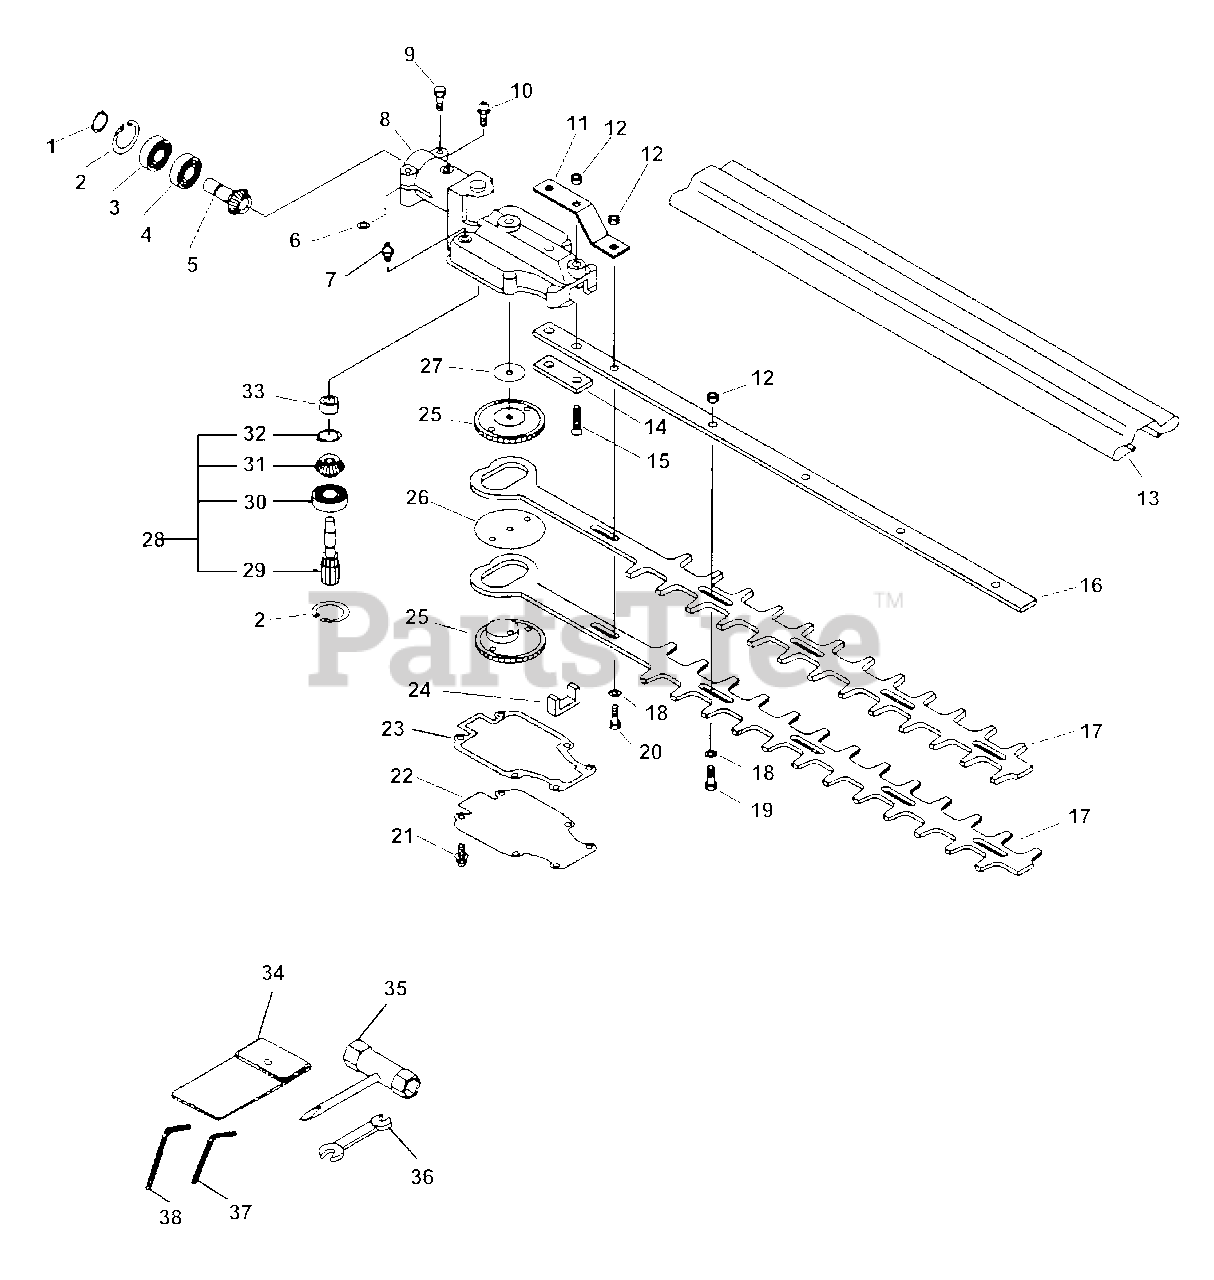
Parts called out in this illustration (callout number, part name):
1	RING, RETAINING - 12
2	RING, RETAINING - 24
3	BEARING, BALL - 6901Z
4	BEARING, BALL - 6901
5	GEAR
7	FITTING, GREASE
8	CASE, GEAR - UPPER
9	SCREW - 5X28
10	SCREW - 5X12
11	BRACKET, BLADE
12	LOCKNUT - 6
13	COVER, BLADE
14	PLATE
15	SCREW - 6X35
16	SUPPORT, BLADE
17	BLADE - 17" (43cm)
18	WASHER - 6
19	BOLT - 6
21	SCREW - 4X12
22	LID, GEAR CASE
23	GASKET, GEAR CASE
24	SEAL, FELT
25	GEAR - SPUR
28	SPUR GEAR ASSY
29	GEAR - SHAFT
30	BEARING, BALL - 6901
31	GEAR - BEVEL -- DRIVEN
32	RING, RETAINING
33	BEARING, NEEDLE
34	BAG, TOOL
35	T-WRENCH - 17X19mm
36	SPANNER - 8X10mm
37	HEX KEY - 3mm
38	HEX KEY - 4mm
